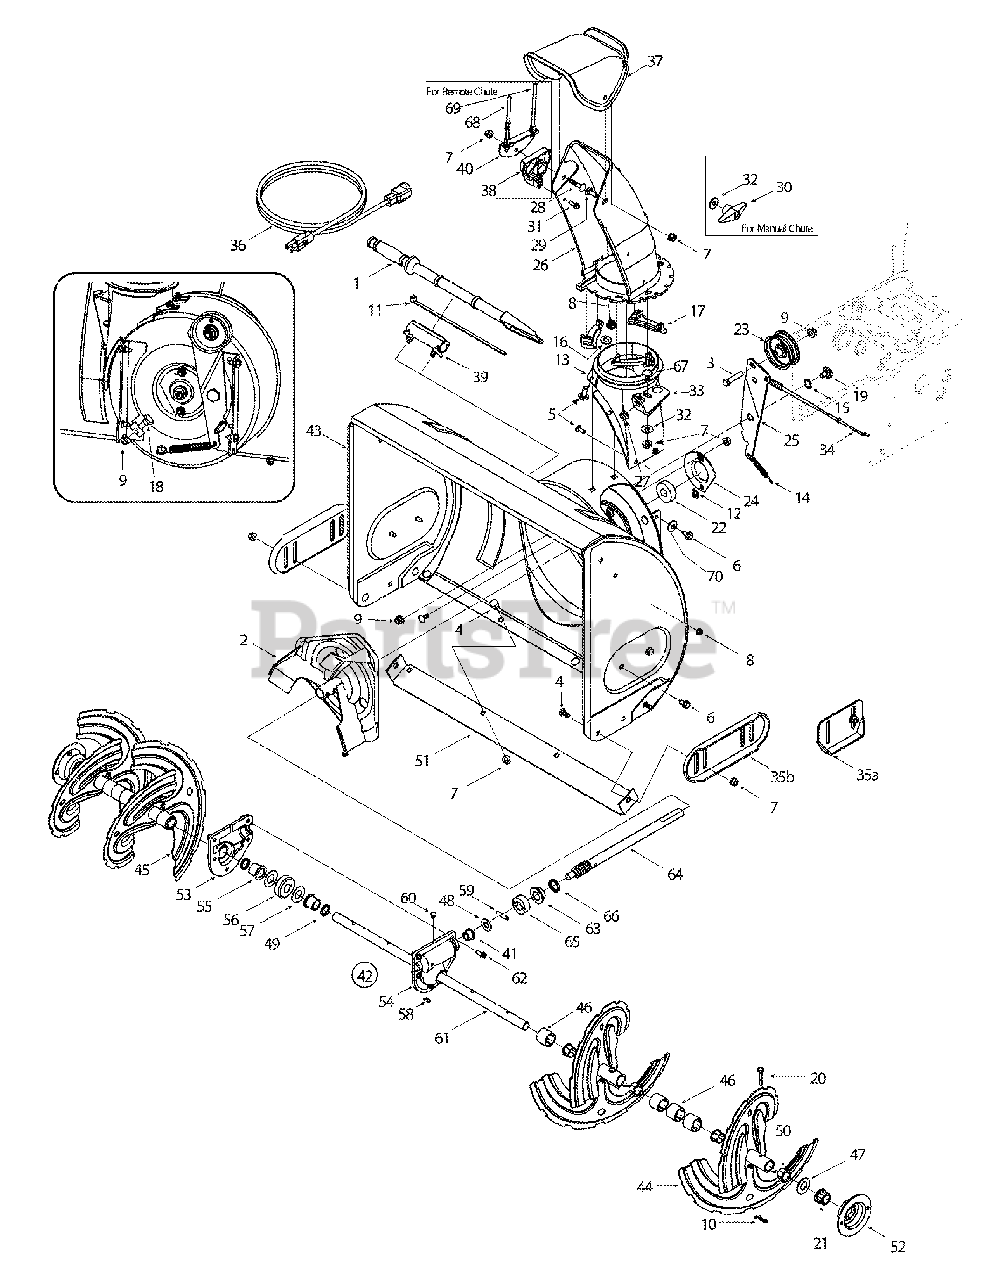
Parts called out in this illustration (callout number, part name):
1	Clean Out Tool
3	Screw, 3/8-16 x 1.75, Gr5, Std
4	Bolt, Carriage, 5/16-18 x.750 Gr1
5	Screw, Carriage, 1/4-20 x.75, Gr5
6	Screw, 5/16-12 x 0.750
7	Nut, Flange Lock, Nylon, 5/16-18, Gr F
8	Nut, Flange Lock, Nylon, 1/4-20, Gr F
9	Nut, Flange Lock, Nylon, 3/8-16, Gr F
10	Pin, Cotter, Bow Tie
11	Cable, Tie, 3/16 x.05 x 7.4
12	Nut, Push-on,.25 Dia
13	Chute, Adapter 5" Dia
14	Spring, Extension,.38 OD x 3.6
15	Washer, Wave,.625 x.885 x.015
16	Washer, Flat,.25 x.630 x.0515
17	Keeper, Flange
18	Screw, Shoulder,.498 x.340, 3/8-16
19	Screw, Shoulder,.625 x.17, 3/8-16
20	Pin, Shear,.25 x1.50, Gr2
21	Bearing, Hex Flange x.75 ID
22	Bearing, Ball,.75 ID x 1.85 OD
23	Pulley, Idler, Flat 2.75 OD
24	Housing, Bearing, 1.85 ID
26	Chute Assembly, Lower, 2-way
27	Plastic Bushing
28	Bolt, Carriage, 5/16-18,.750, Gr1
28	Bolt, Carriage, 5/16-18, 1.50, Gr2
29	Bolt, Carriage, 5/16-18, 1.00
30	Knob Assembly
31	Screw, 1/4-15 x 0.75
32	Flat Washer,.349 x.879 x.063
34	Auger Clutch Cable, 44.75"
36	Extension Cord, 3-Prong
37	Upper Chute, Manual
37	Upper Chute, Remote
38	Cable Guide, Chute Tilt
39	Mount, Clean Out Tool
41	Bearing, Flange,.75 ID x 1.00 OD x.925
42	Gearbox Assembly, Auger, 24"
42	Gearbox Assembly, Auger, 28"
42	Gearbox Assembly, Auger, 30"
46	Spacer, 1.25 OD x.75 ID x 1.00
47	Washer, Flat,.76 x 1.49 x.06
48	Washer, Flat,.51 x 1.12
49	Seal, Oil,.750 ID
50	Bushing, Flange,.800 ID x.910 OD
53	Housing Assembly, Auger, RH Reducer
54	Housing Assembly, Auger, LH Reducer
55	Bearing, Flange,.75 ID x 1.00 OD x.975
56	Gear, Worm 20T
57	Washer, Flat,.760 ID x 1.5 OD
58	Key, Hi-pro 3/16 x 5/8
59	Pin, Dowel,.25 OD x 1.2
60	Plug, 1/4 x.437
61	Axle, Auger, 24"
61	Axle, Auger, 28"
61	Axle, Auger, 30"
62	Screw, Self-tapping, 1/4-20, 0.750
63	Bearing, Flange,.75 ID x 1.00 OD x.59
64	Shaft, Worm.75 OD
65	Collar, Thrust
66	Seal, Oil,.75 x 1 x.131
67	Carriage Screw, 5/16-18 x 1.00
68	Chute Deflector Cable w/Clip
69	Chute Deflector Control Cable
70	Bell Washer
